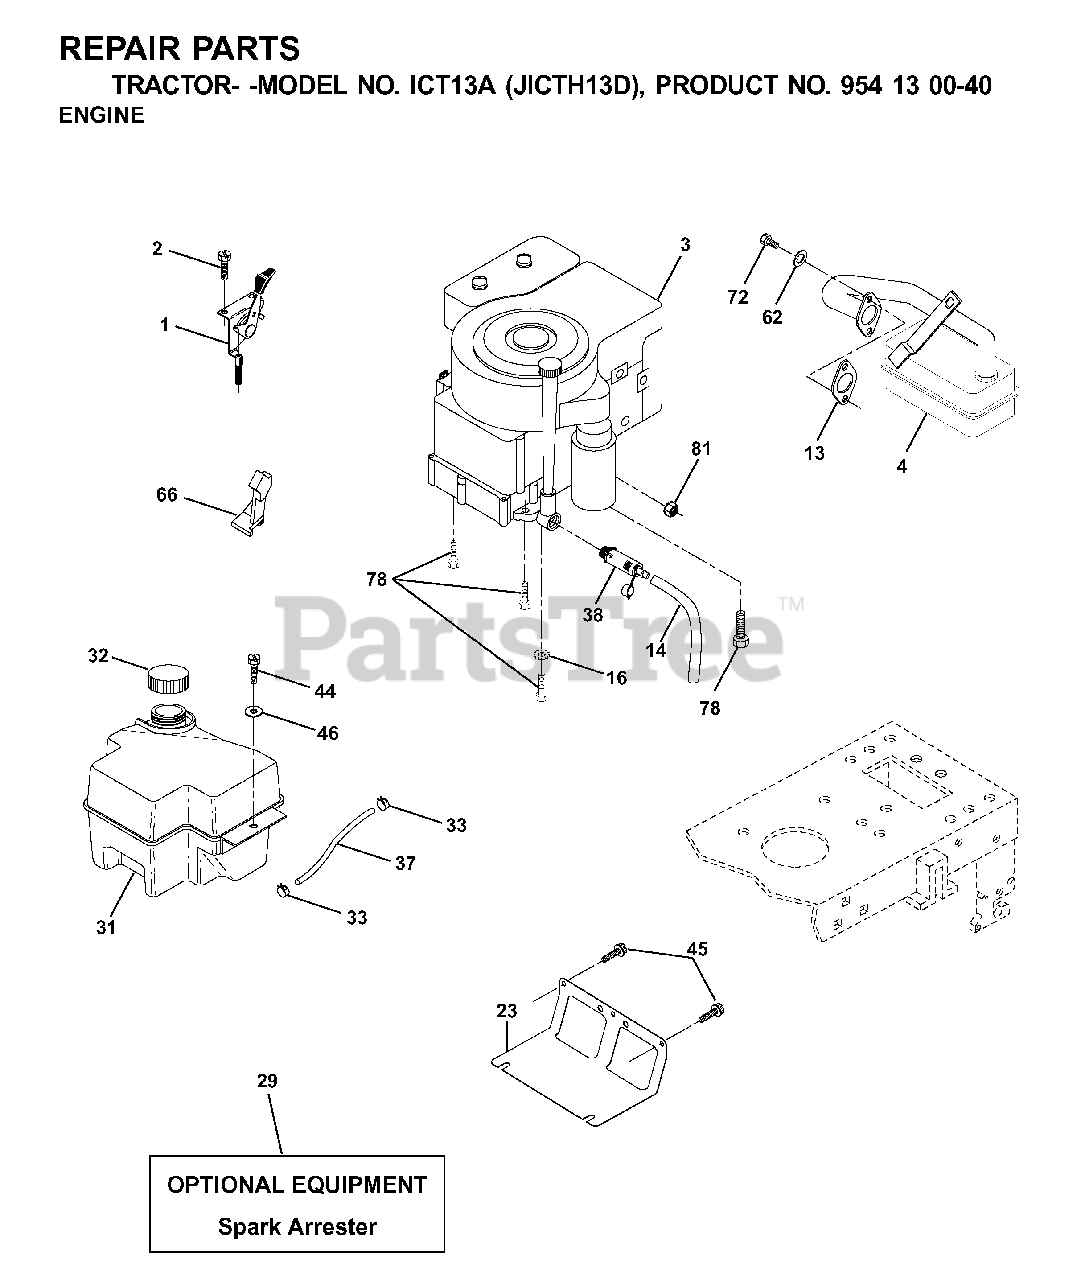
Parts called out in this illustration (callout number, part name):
1	THROTTLE CONTROL CABLE
2	SCREW LT
13	REPL BY 532 27 22-93
14	TUBE, DRAIN OIL ASM.
16	LOCKWASHER
23	SHEILD.BROWNING.DBR.GUARD
29	ARRESTER SPARK (OPTIONAL)
31	TANK, 2GAL
32	FUEL CAP
33	HOSE CLAMP
37	LINE.FUEL.20
38	PLUG, OIL DRAIN EASY
44	SCREW HEXWSHR 1/4-20X3/4
45	SCREW, 3/8-16X3/4
62	LOCKWASHER
66	STOP THROTTLE
72	SCREW
78	SCREW.3/8-16
81	NUT
